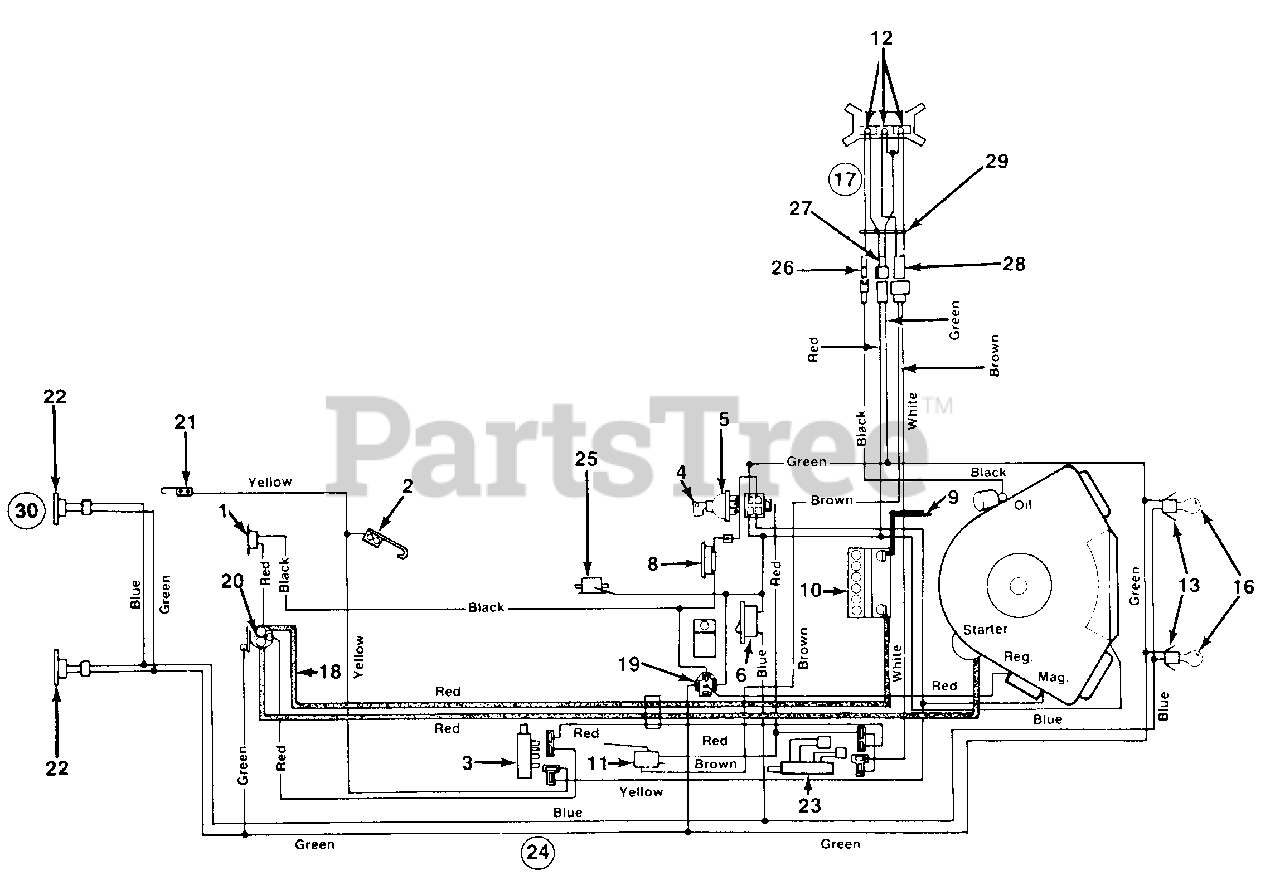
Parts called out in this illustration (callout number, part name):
1	Circuit Breaker
2	Spring Switch
3	Safety Switch Dpst.
4	Ignition Key
5	Ignition Switch
6	Headlight Switch
8	Ammeter
9	Ground Wire 14.0" Lg.
10	12 Volt Battery
11	Safety Switch
12	Bulb
13	Socket
16	Lamp
17	Wire Harness
18	Electric Wire 27.0" Lg.
19	Relay
20	Solenoid
21	Spring Switch
22	Taillight
23	Safety Switch
24	Wire Harness
25	Fuel Pump
26	Connector
27	Connector
28	Connector
29	Clamp
30	Taillight Bulb
